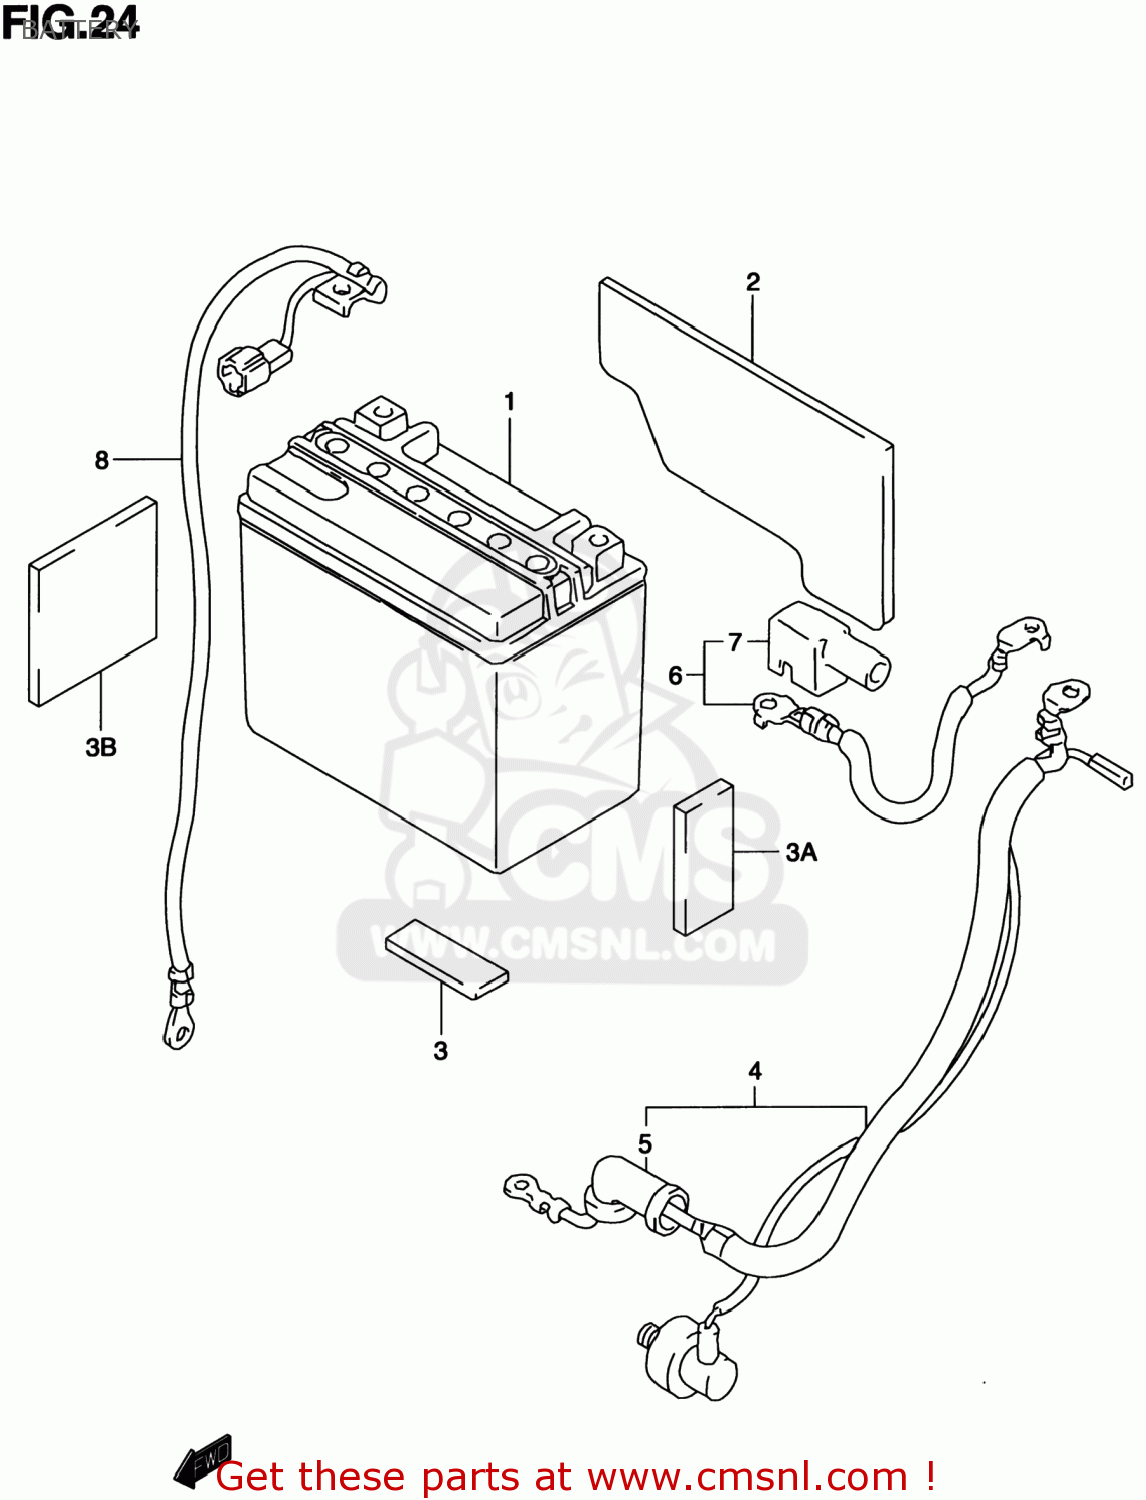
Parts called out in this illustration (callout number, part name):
1	BATTERY ASSEMBLY (12V) FTX
2	PROTECTOR(170X95X3.0)
3	PROTECTOR(20X50X8)
3A	CUSHION 20X45X6
3B	PROTECTOR(50X50X5)
4	WIRE,STARTER MOTOR LEAD
5	CAP,STARTER MOTOR LEAD
6	WIRE,BATTERY PLUS LEAD
7	CAP,BATTERY PLUS
8	WIRE,BATTERY MINUS
